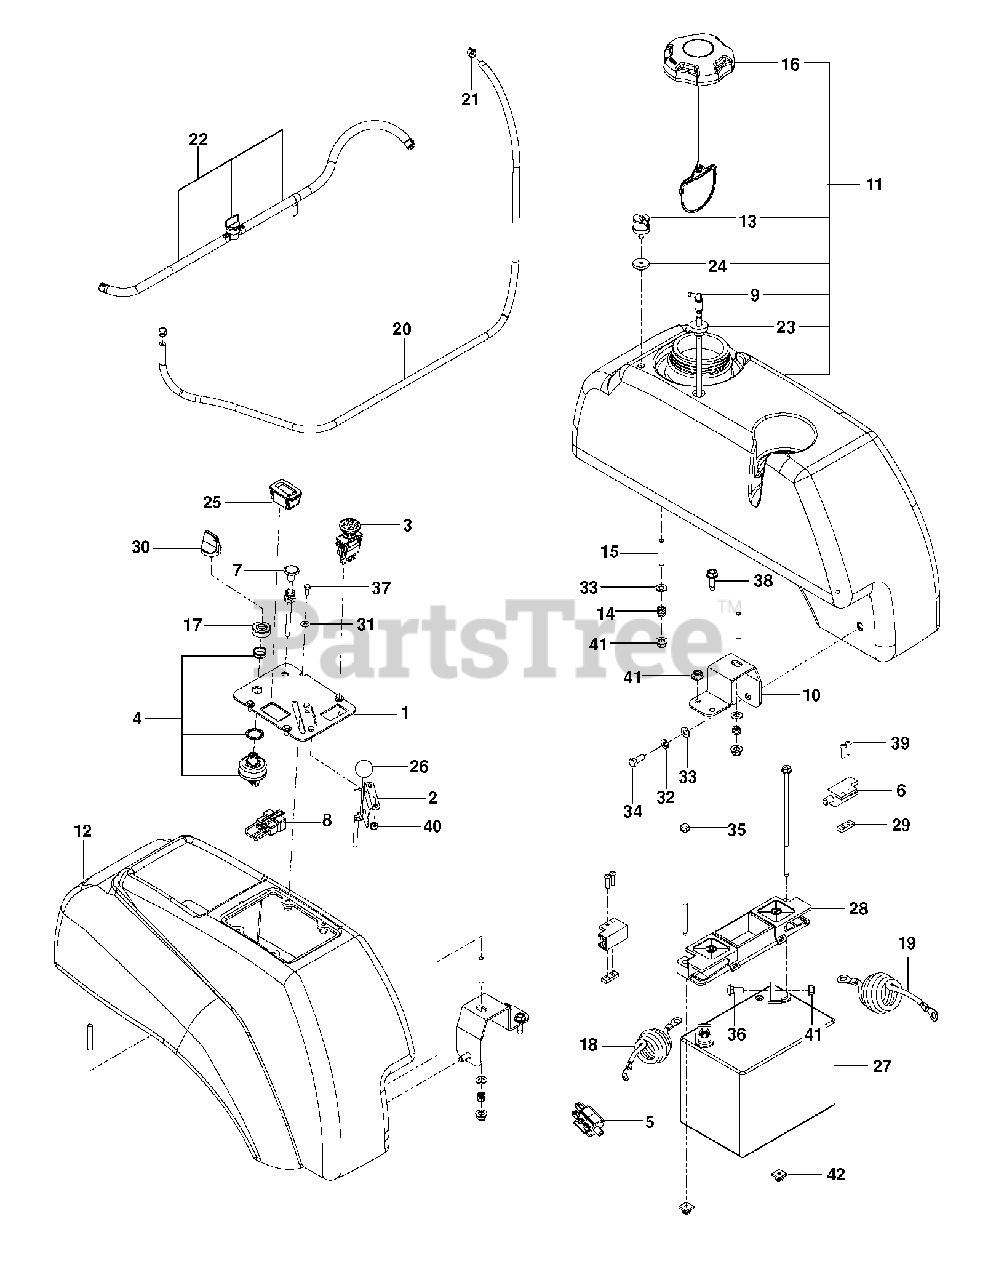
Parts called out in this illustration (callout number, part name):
1	PLATE, CONSOLE, BLK
2	THROTTLE CONTROL W/BALL KNOB
3	SWITCH, PTO 10 AMP
4	SWITCH, IGNITION, INDAK
5	SWITCH, BRAKE 3P
6	SWITCH INTERLOCKT
7	Choke Control Cable, 57"
8	PLUG, TIMER
9	FITTING, FUEL
10	SUPPORT, TANK, BLK
11	TANK ASM LT MZ BLK
12	Console, RT-BLK
13	VALVE.FUEL.CHECK
15	STUD, 5/16C
16	CAP, FUEL
17	CAP IGNITION NUT
18	POST.CABLE LONG
19	NEG. CABLE, 28"
21	CLAMP, HOSE
22	Fuel Line Assembly
23	RUBBER GROMMET
24	GROMMET, CHECK VALVE
25	Hour Meter Gauge
26	KNOB ROUND BALL
27	BATTERY, 12 V 330 AMP TBR
28	BATTERY HOLD DOWN
29	TAPPED PLATE
30	KEY, IGNITION
31	WASHER
32	Lock Washer, 5/16
33	WASHER
34	BOLT
35	BOLT - 1/4-20 X 7.5
36	BOLT 5/16C X 3/4" CARRIAGE
37	HCS #10-24 X 1/2
38	SCREW
39	SCR #10-24 X .75 SKT HD BLK
40	NUT 10-24 NYLOC
41	5/16-18 NYLOC FLANGE NUT
42	PUSH NUT-NYLON
